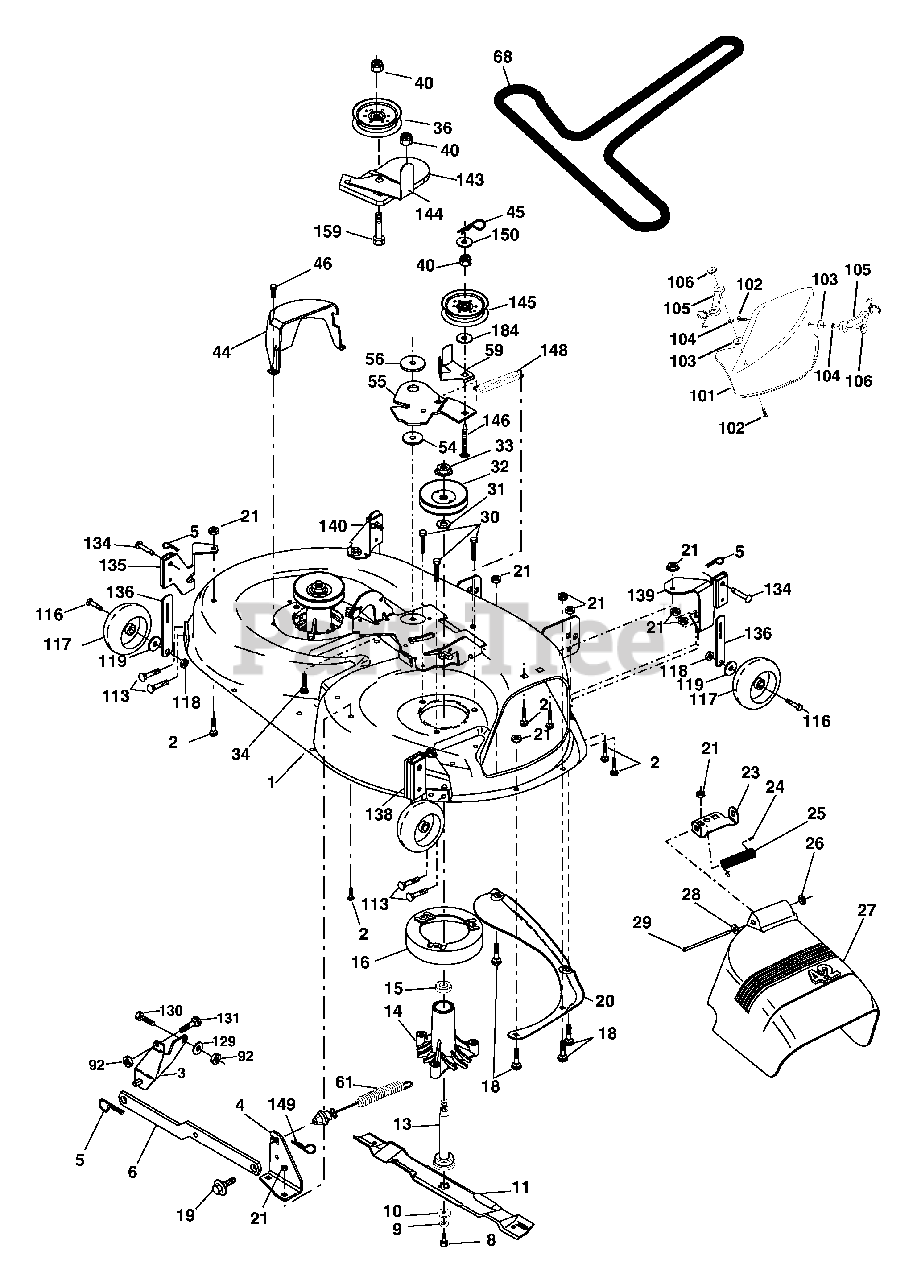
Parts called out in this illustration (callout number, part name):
1	Mower Deck Assembly, 42"
2	Bolt
3	Bracket Asm Fr. Sway Bar 3/42
4	Bracket Asm Deck 42" Sway Bar
5	Retainer Spring
6	Bar Sway Deck
8	Bolt 3/8-24 x 1.25 Gr. 8 patched
9	Washer, Lock
10	Washer, Hardened
11	Blade, Mulching 42" Std
11	Blade Mower 42" Hi-Lift
11	Blade Mulching 42" Premium
13	Shaft Assembly, Mandrel, Vented
14	Housing, Mandrel, Vented
15	Bearing, Ball, Mandrel
16	Stripper, Mandrel Deck
18	Bolt, Carriage 5/16-18 x 5/8
19	Bolt, Shoulder
20	Baffle, Vortex
21	Nut
23	Bracket, Deflector Mower 42"
24	Cap, Sleeve 80 x 112 Blk Mower
25	Spring, Torsion, Deflector 2 52
26	Nut, Push Phos & Oil
27	Shield, Deflector 42" Blk
28	Washer 11/32 x 5/8 x 16 Ga.
29	Rod, Hinge 42" 6 75 W/G
30	Screw Thdrol
31	Washer, Spacer Mower Vented
32	Pulley, Mandrel
33	Nut, Toplock
34	Bolt Carr SH 3/8-16 x 1-1/2 Gr.5
36	Pulley, Idler, Flat
40	Nut Lock 3/8-16
44	Guard, Mandrel, LH
45	Retainer
46	Screw, Thdrol 1/4-20 x 5/8 T
54	Washer, Hardened
55	Arm, Idler
56	Spacer, Retainer
59	Guard TUV Idler
61	Spring Ext Elect. Clutch
68	V-Belt, 42" Mower
92	Nut Lock Hex w/Ins 3/8-16 unc
101	Mulcher Cover
102	Screw, Pan Hd Phillip 10-24 x 5/8
103	Washer, Flat
104	Washer, Lock
105	Latch Assembly
106	Nut, Weld
113	Bolt 5/16-18 Hex Wsh Hd Lock
116	Bolt, Shoulder
117	Wheel, Gauge
118	Nut Centerlock 3/8-16
119	Washer 3/8 x 7/8 x 14 Ga.
129	Washer 13/32 x 13/16 x 12 Ga.
130	Bolt Fin HEx 3/8-16 unc x 1 Gr. 5
131	Bolt RDHD SQNK 3/8-16 unc x 1
134	Pin Head Rivet
135	Bracket Asm. Whl Ga. R LH
136	Bar Adjusting Gauge Wheel
138	Bracket Asm Whl Ga. R RH
139	Bracket Asm. Whl Ga. F RH
140	Bracket Asm Whl Ga. F LH
143	Bracket Arm Idler 42"
144	Keeper Belt 42" Clutch Cable
145	Pulley Idler Flat
146	Bolt Carriage Idler
148	Spring Return Idler
149	Retainer Spring Yellow
150	Washer 9/32 x 3/4 x 10 Ga.
159	Bolt Rdhd Sqn 3/8-16 unc x 1-3/4
184	Washer 13/32 x 7/8 x 10 Ga.
